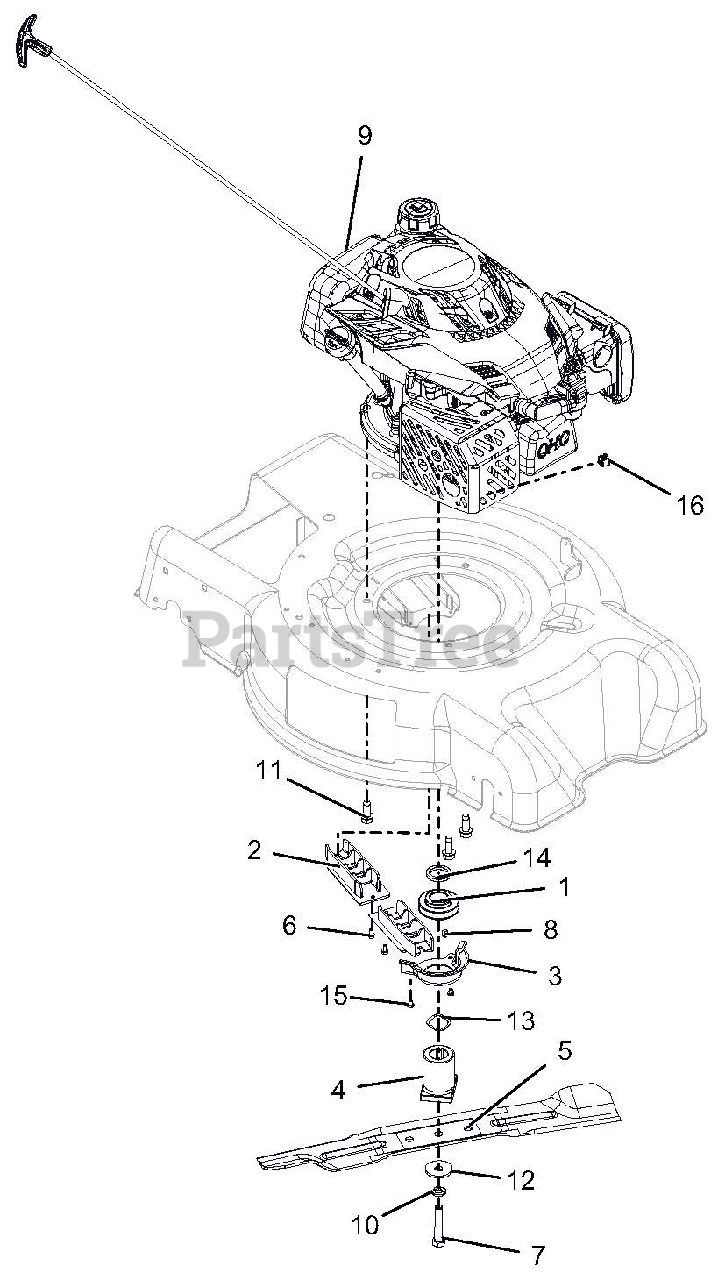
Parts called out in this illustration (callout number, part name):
1	PULLEY, GROUND DRIVE, LM
2	GUIDE, BELT INNER
3	GUIDE, BELT CRANK
4	ADAPTER, BLADE
5	BLADE, MOWER 21" HIGH LIFT
6	SCR-TAP 10-24X.375 PRE-COAT 80
7	@BLT-HEX .4375-20X2.25 GR8 YWZ
8	KEY-SQ .188X.188X.375
9	ENGINE, SUBARU 175CC VERT
10	@WSHR-LK .44X.109 REG YWZC
11	@SCR-TAP .38-16X1.00 HWH TR YZ
12	WSHR-FL-STL .4375X1.50X.125 YZ
13	WASHER - WAVE 1.09X1.37X.016
14	SPCR, 1.00 X 1.375 X .179
15	SCR-TAP 10-24X.25 CRSLPH TR YZ
16	PLUG, DOME-BLACK, .625 DIA
